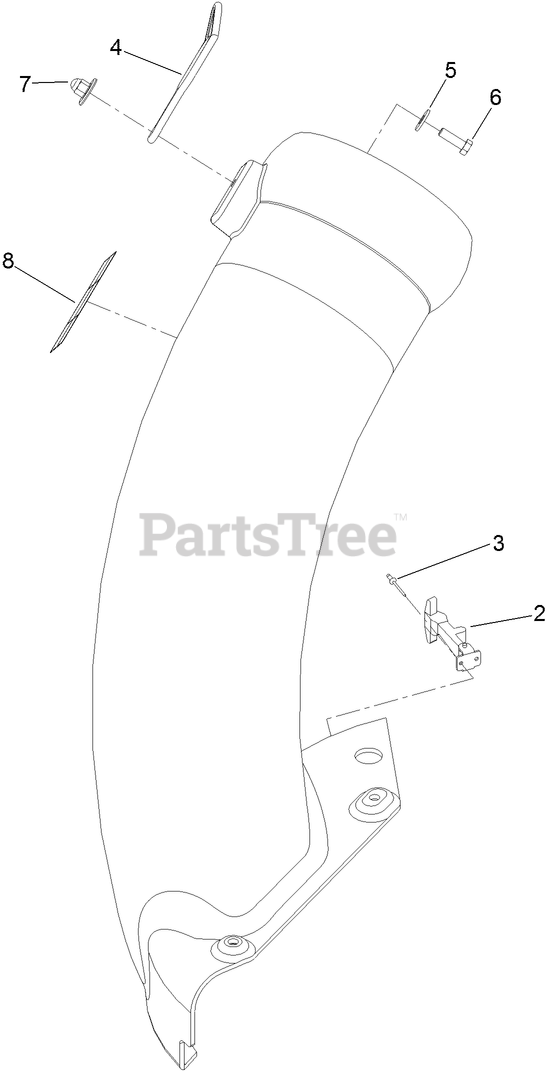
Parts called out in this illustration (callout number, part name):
2	HANDLE ASM
3	RIVET-POP
4	RETAINER-DUCT
5	WASHER-FLAT
6	SCREW-HH
7	NUT-IMPELLER
8	DECAL-DANGER
